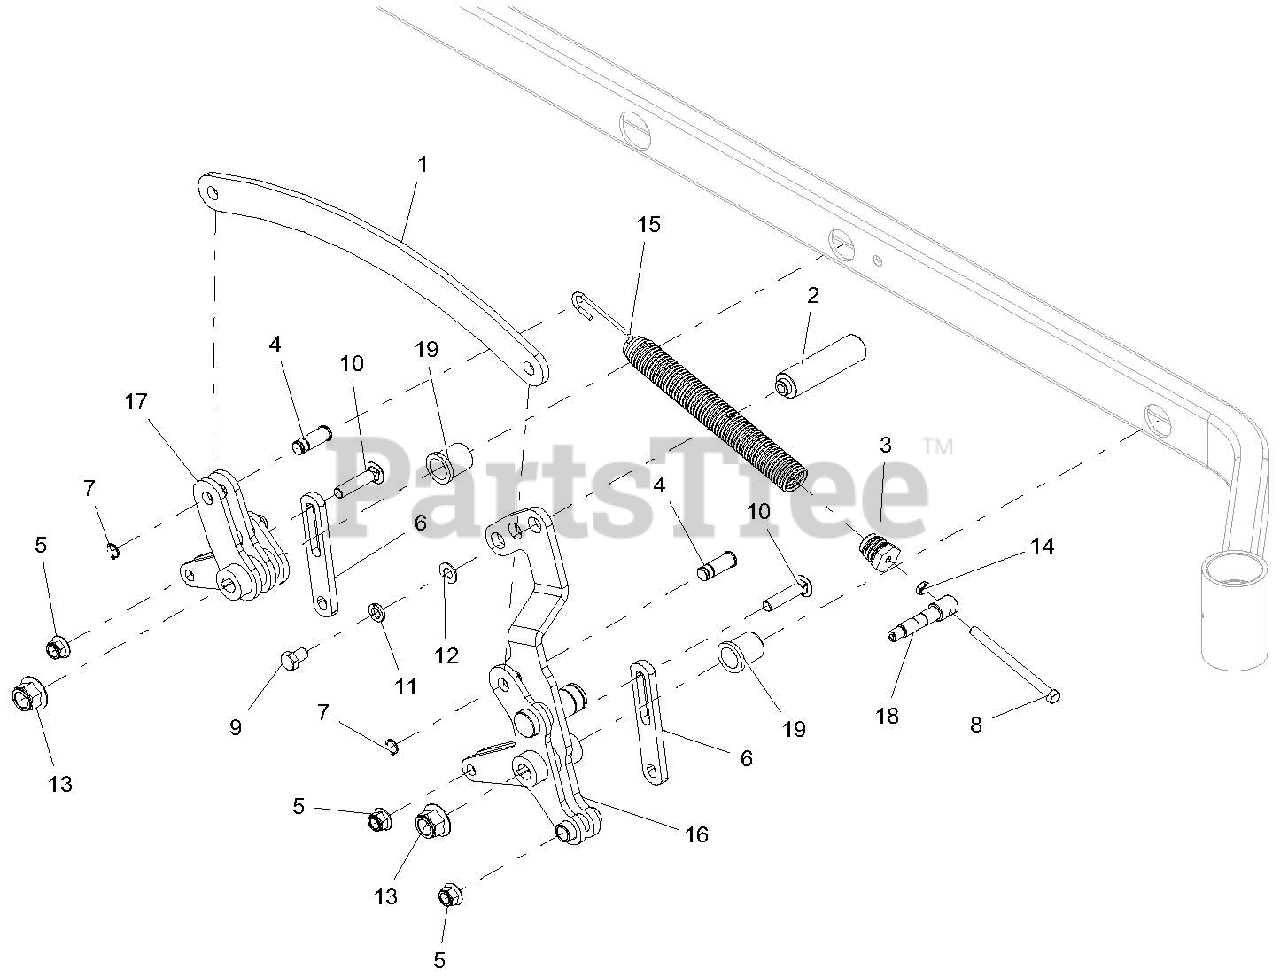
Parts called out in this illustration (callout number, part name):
1	LIFT, LINK - BLACK
2	PEDAL, LIFT
3	PLUG, SPRG
4	PIN, CLEVIS .625 SNAP RING
5	NUT-LK-NYL-FLG .50-13 YWZC
6	LINK, DECK LIFT - LONG
7	RG-RTNG-EXT .625x.050
8	BLT-HEX .38-16X5.00 GR5 YWZC
9	BLT-HEX .50-13X.75 GR5 YWZC
10	BLT-RDHDSQNK .50-13X2.25 G5 Y
11	WSHR-LK .50X.125 REG YWZC
12	WSHR-FL-STL .505X1.00X.062 YWZC
13	NUT-LK-NYL-FLG .75-10 YWZC
14	NUT, JAM .375-16 YWZC
15	SPRG, DECK LIFT
16	WLDMT, PT400 FRONT RH DECK LIFT ARM-BLACK
17	WLDMT, PT400 REAR RH DECK LIFT ARM-BLACK
18	TRUNION, SPRG
19	BSHG-FLG 1.00X1.25X1.5X1.5
